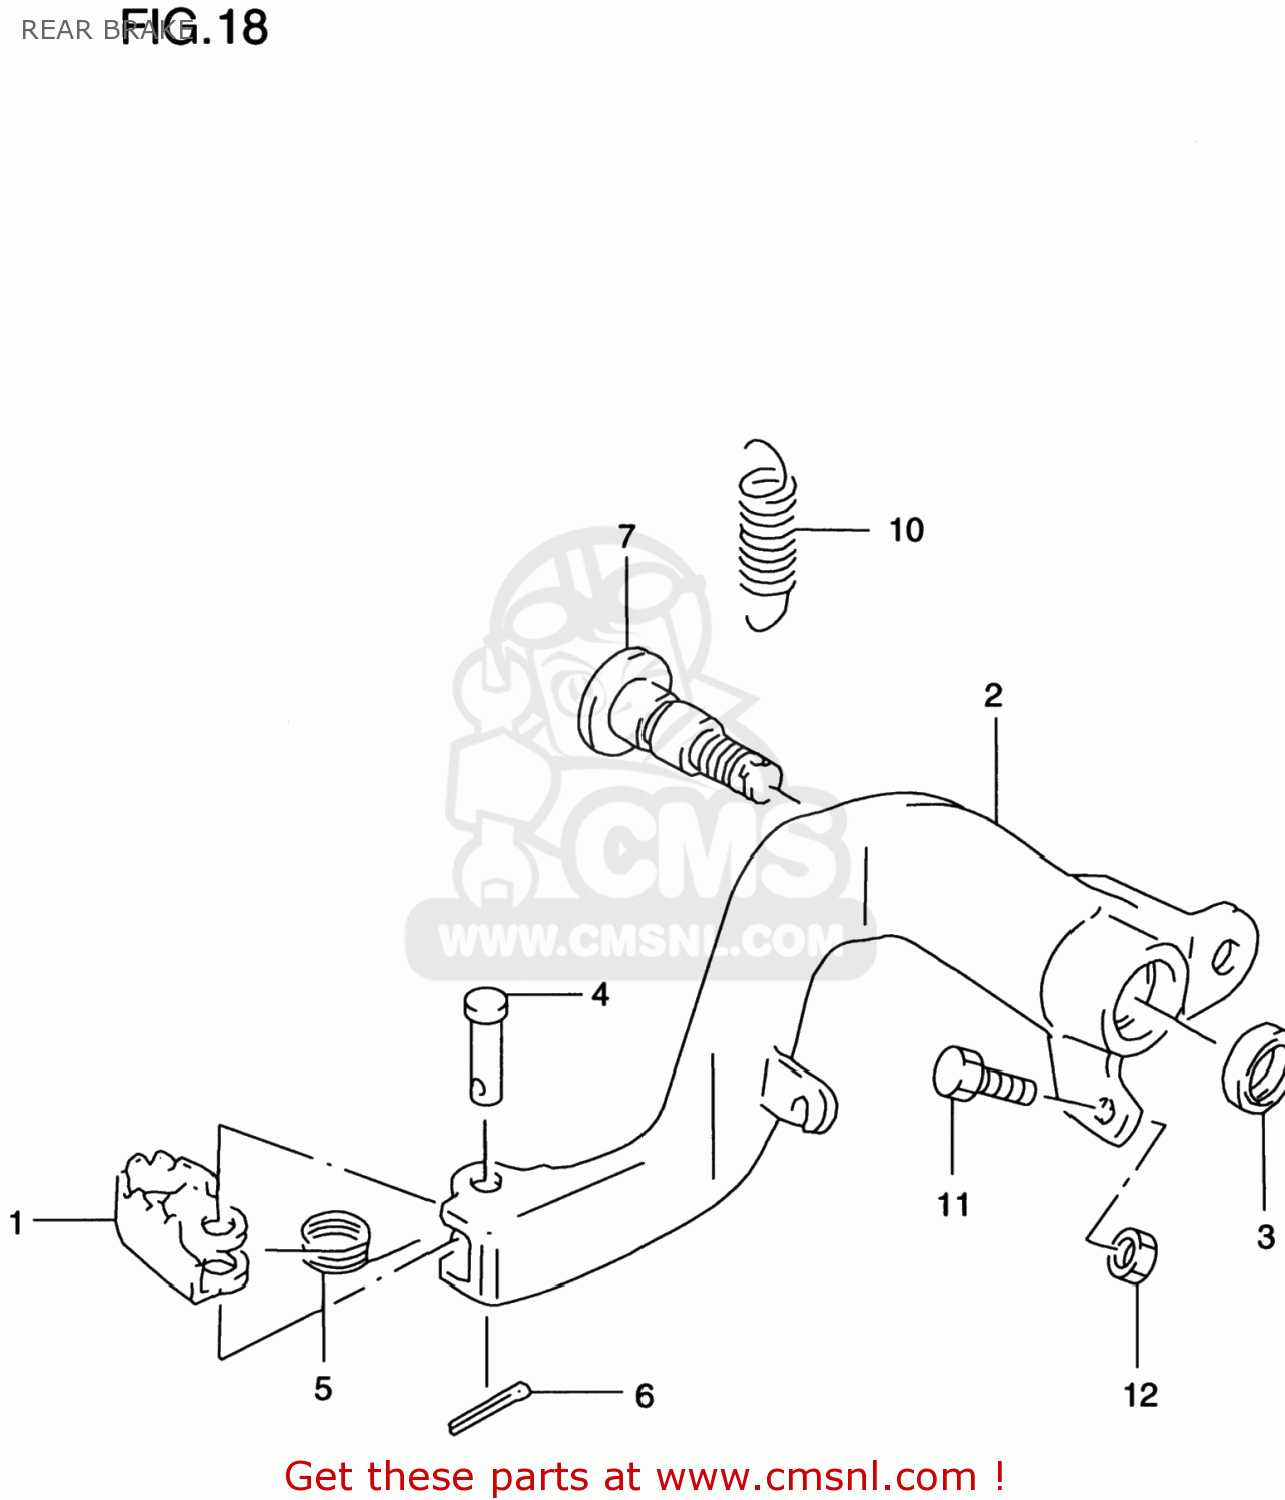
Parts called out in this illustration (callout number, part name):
1	PEDAL,BRAKE
2	ARM,BRAKE PEDAL
3	SEAL,OIL(15X21X3)
4	PIN(6X23.5)
5	SPRING
6	PIN
7	SHAFT,BRAKE PEDAL
8	WASHER
9	PIN 20X20
10	SPRING,BRAKE PEDAL RETURN
11	BOLT(6X23)
12	NUT 6MM
